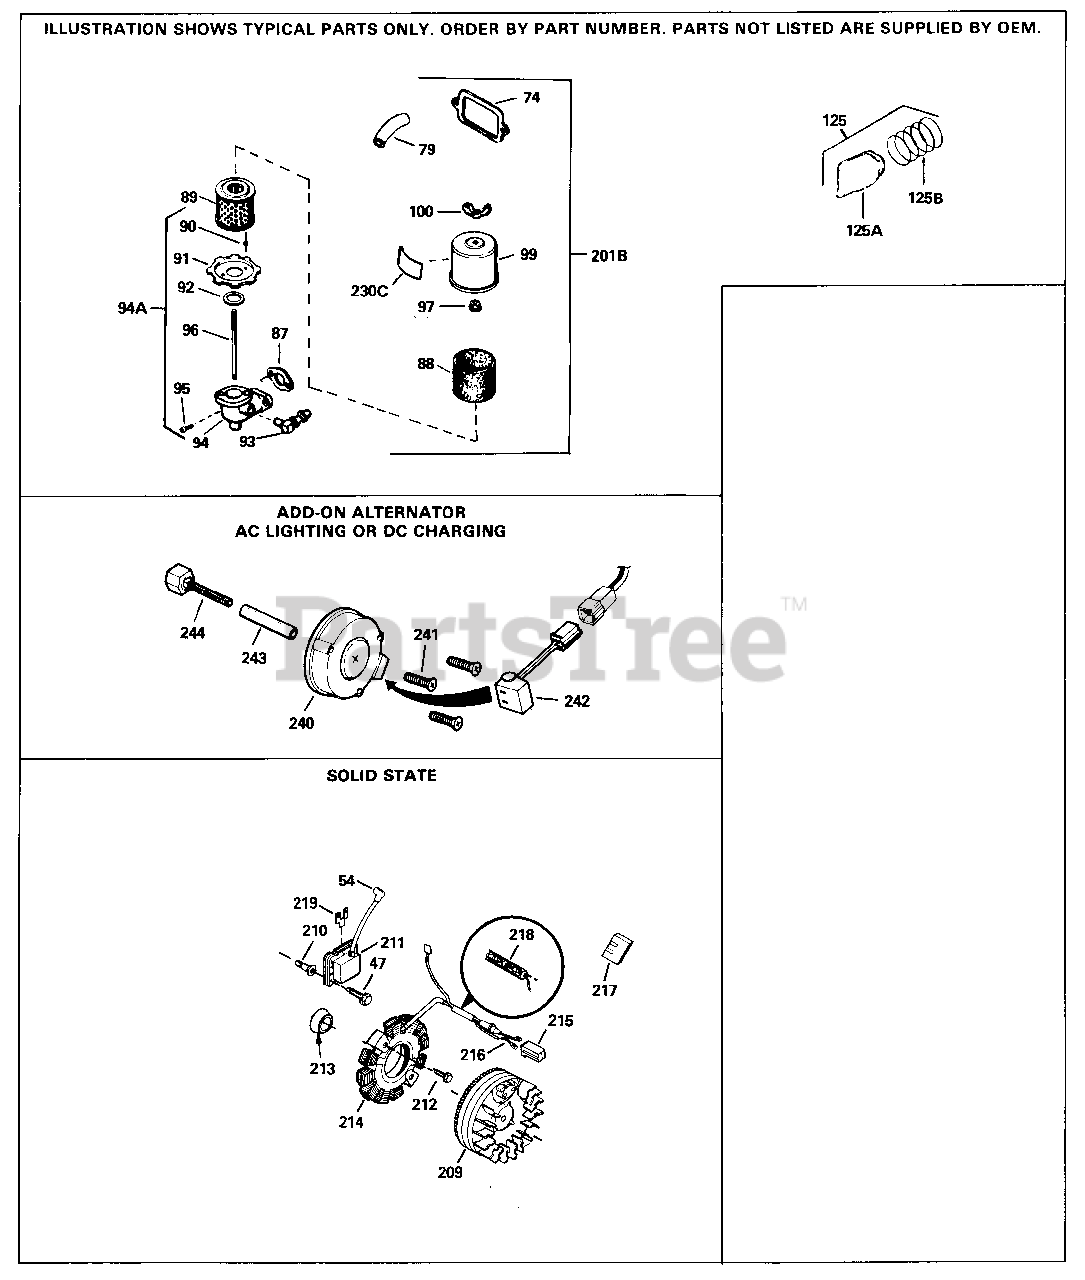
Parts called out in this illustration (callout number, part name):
35	Spool, Governor
47	Screw, 1/4-20 x 5/8"
54	Cover, Spark plug (Use as required)
74	Valve Cover Gasket
79	Breather Tube
87	* Air Cleaner Gasket (Use as required)
87	Spacer, Cleaner (Use as required)
94A	Elbow Assy., Air cleaner (Incl. 90,91 ,92,93,94,96) (Use in 730561 assembly only)
201B	Air Cleaner Kit (Incl. 74,79,80,87,88 ,89,90,91,92,94,95,96,97,99,100 & 230 C) (Used only on engine with an exter nally vented fully adjustable carbure tor)
240	Alternator (Optional)
241	Screw, 8-18 x 1-1/8" (3 required) Opt .
242	Connector, A.C. Lighting (Optional)
242	Connector, D.C. Charging (Optional)
243	Tube, Centering (Optional)
244	Alternator Shaft (Optional)
